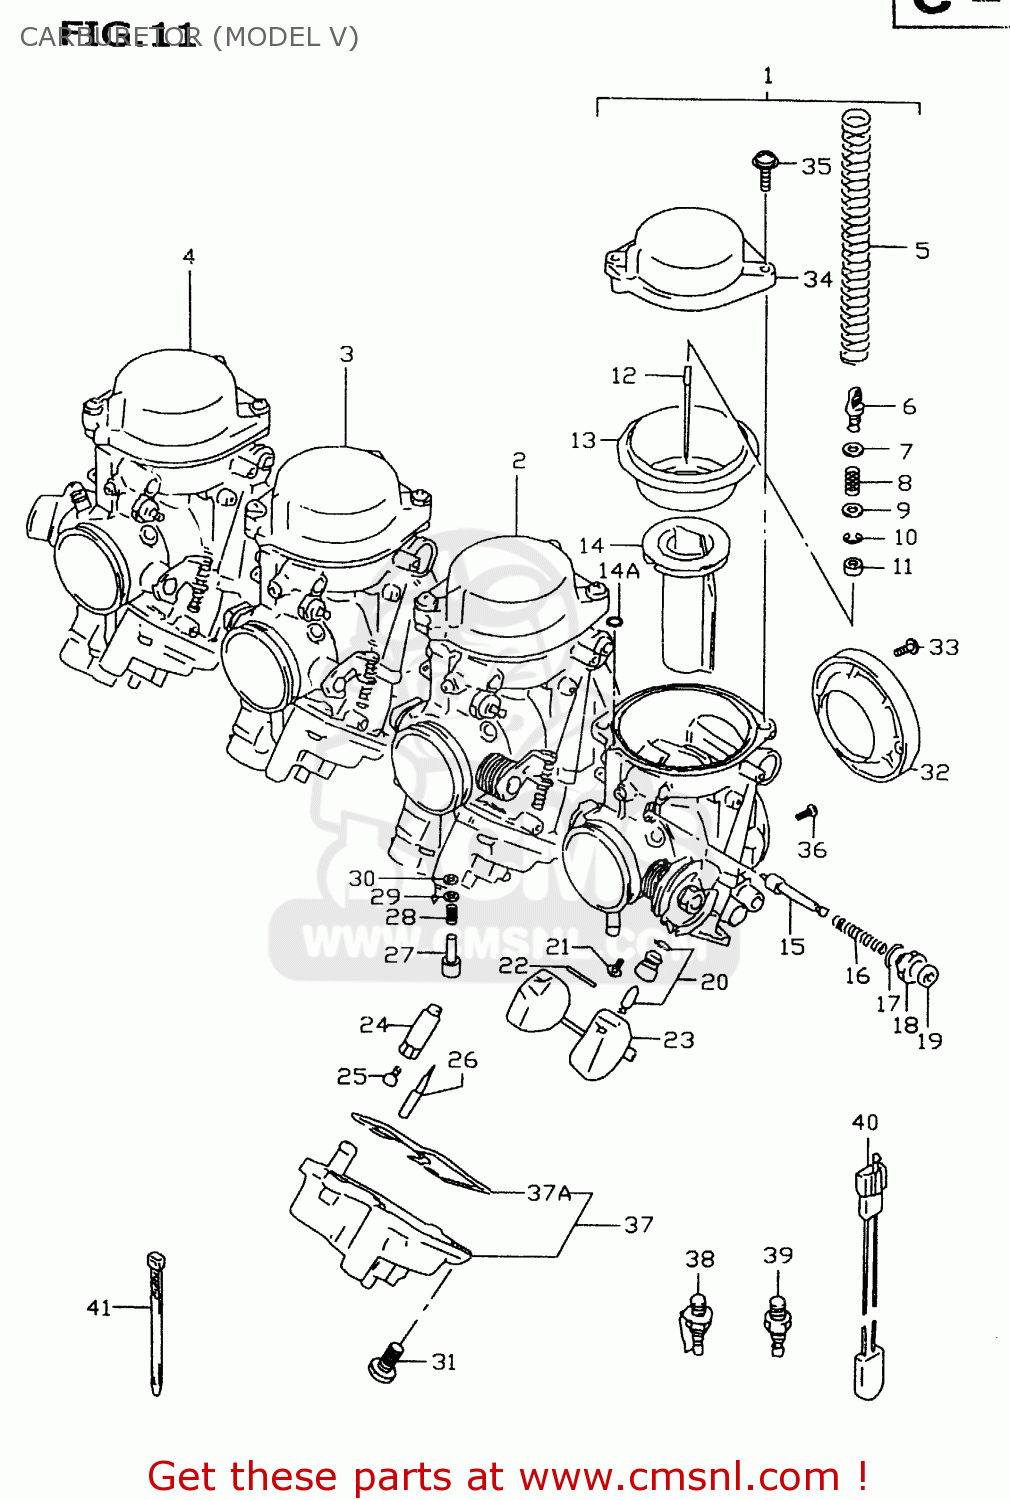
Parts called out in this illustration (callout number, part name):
1	CARBURETOR ASSY,L
2	CARBURETOR ASSY, ML
3	CARBURETOR ASSY, MR
4	CARBURETOR ASSY, RH
5	SPRING
6	HOLDER
7	O RING(D:1.9,ID:4.8)
8	SPRING
9	WASHER
10	E RING,MULTIPLE JET NOZZLE
11	RING
12	NEEDLE,JET
13	DIAPHRAGM
14	VALVE,PISTON
14A	O RING
15	PLUNGER
16	SPRING
17	O RING
18	GUIDE SCREW,PLUNGER
19	CAP,STARTER VALVE
20	VALVE ASSY,NEEDLE(NI)
21	SCREW
22	PIN,FLOAT
23	FLOAT ASSY
24	HOLDER,JET
25	JET,MAIN(125)
26	JET,PILOT(12.5)
27	ADJUSTER
28	SPRING,THROTTLE SCREW
29	WASHER
30	O RING,PILOT AIR SCREW
31	SCREW
32	FUNNEL
33	SCREW
34	COVER ASSY,DIAPHRAGM
35	SCREW
36	JET,MAIN(125)
37	BODY ASSY,FLOAT,L
37A	O RING
38	HEATER ASSY,CARBURETOR(15W)
39	HEATER, CARB.
40	THERMO SWITCH,CARB HEATER
41	CLAMP(L:125)
